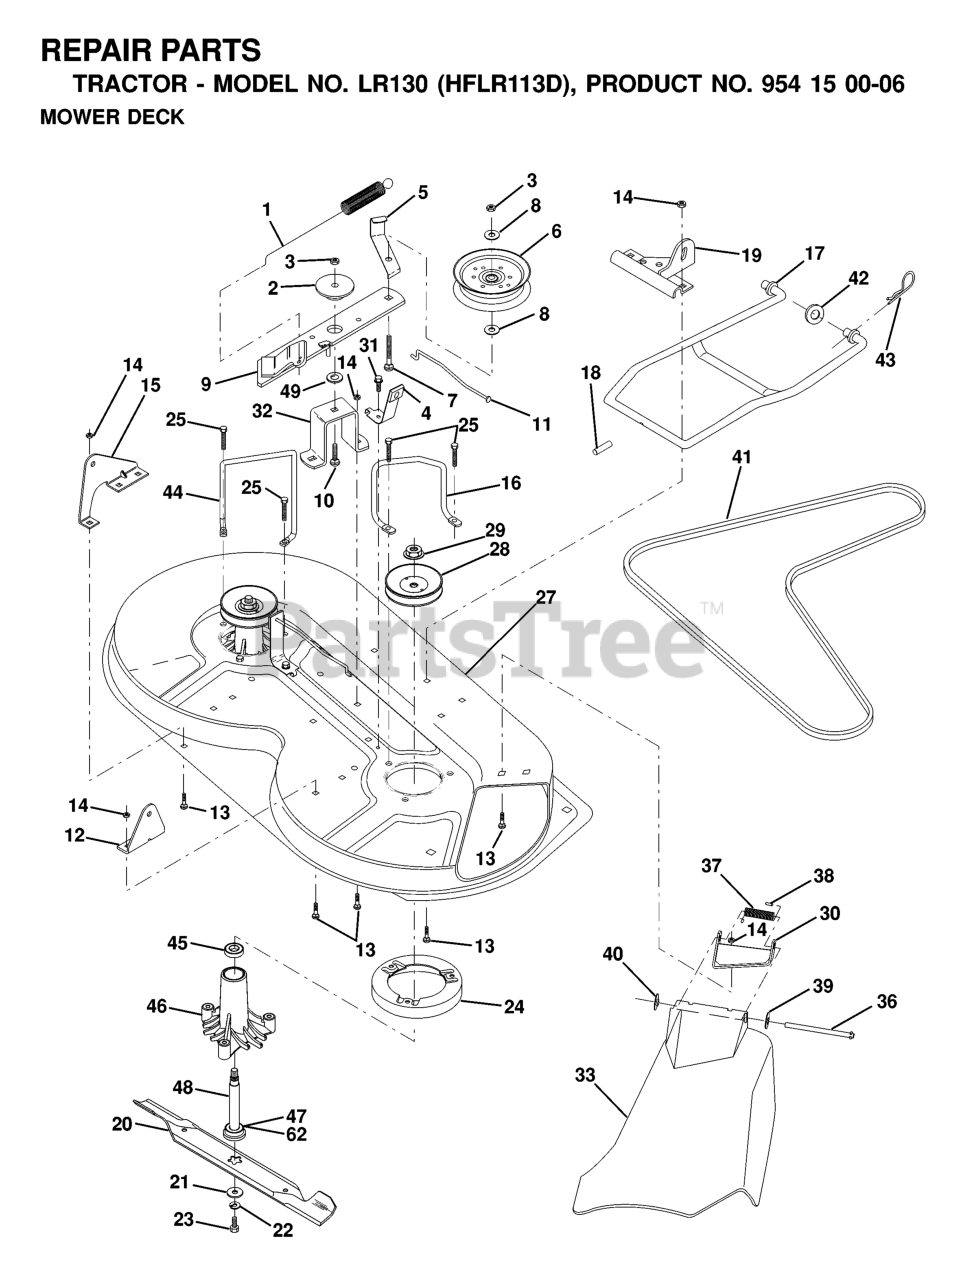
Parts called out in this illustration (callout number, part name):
1	SPRING-MOWER CLUTCH
2	SPACER.RETAINER.MOWER
4	BRAKE ASSEMBLY
5	IDLER BELT GUIDE
6	PULLEY.IDLER.FLAT.MOWER.BLK.PT
8	WASHER
9	IDLER ARM ASSY
10	BOLT.3/8-14X1.25
12	BRKT LIFT REAR
13	RP BOLT 5/16-18 X3/4 ZN/YEL GR
14	LOCKNUT
15	BRKT LIFT REAR LH
16	BELT KEEPER
17	MOWER LINK STABILIZER
18	PIN GROOVE
19	BRKT LINK STABILIIZER
20	BLADE, HI-LIFT 36" PREMIUM
21	WASHER.BLADE
22	LOCKWASHER
23	BLADE BOLT
24	STRIPPER
25	SCREW THDROL ROLLING WASHER HD
27	MOWER HOUSING
28	PULLEY, MANDREL
29	NUT
30	BRACKET ASM DEFLECTOR
31	Screw 5/16-18 x 1/2 Hex, Self Tapping 5/16-18 x 1/2
32	SUPT,IDLER ARM
36	HINGE ROD
37	SPRING TORSION
38	CAP-SLEEVE LT
39	Washer 11/32 x 5/8 x 16 Ga SD
40	NUT PUSH M
41	BELT
42	WASHER
43	SPRING RETAINER
46	HOUSING.MANDREL.VENTED (MACHD)
47	BEARING.BALL.#6204.(MANDREL)
48	SHAFT ASM VENT
49	HARDENED WASHER
62	WASHER FELT
